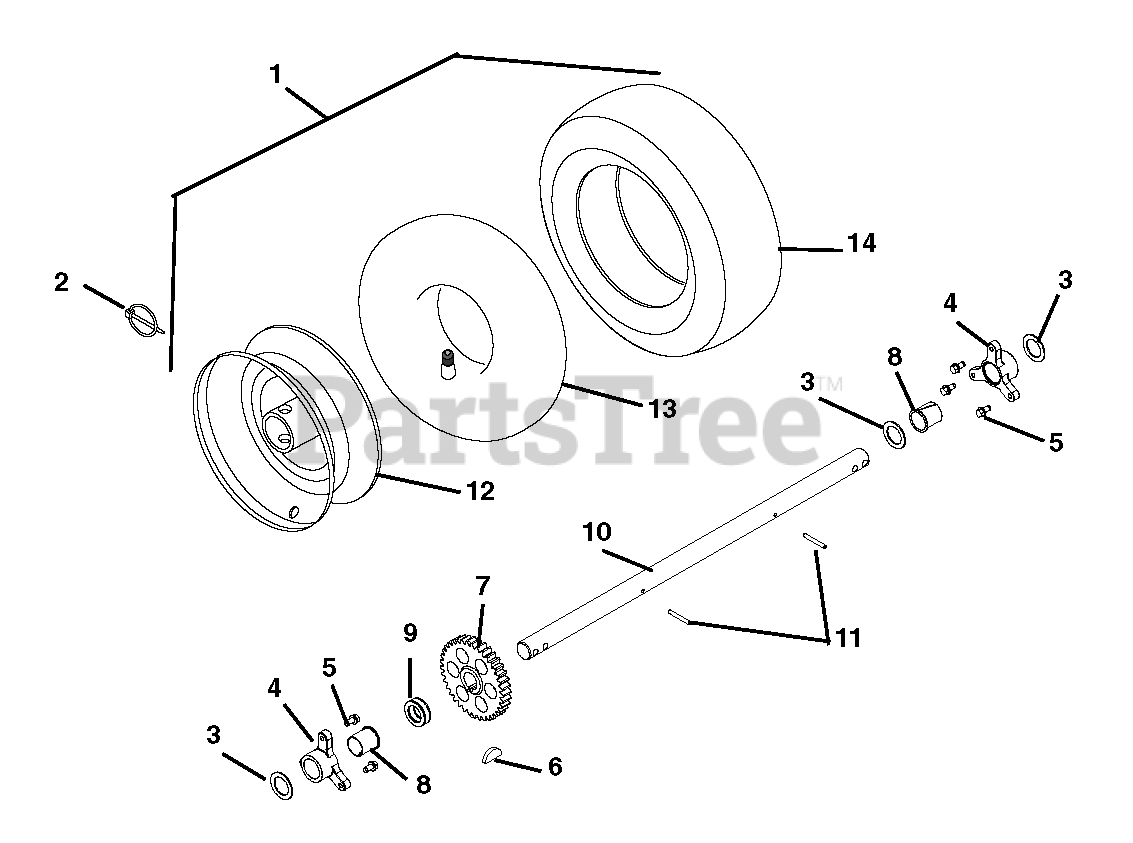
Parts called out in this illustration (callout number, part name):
1	TIRE/WHEEL, RH 15X5.00-6 PIN
1	TIRE/WHEEL, LH 15X5.00-6 PIN
2	PIN-LOK .31X2.00
3	WSHR-FL-STL 1.010X1.505X.062YZ
4	BUSHING, RAKE SHAFT 1"
5	SCR-TAP .25-20X.50 HWH TR YWZ
6	KEY-WDRF .25X.750X.313 SAE91
7	GEAR, SPUR
8	BSHG-FLG SPLIT NYLINER 1.0" HP
9	BUSHING, .50X.68X.50X.75 SLV
10	AXLE, 1.00" SOLID
11	PIN-ROLL .188X1.50
13	TUBE 15 X 5.00-6
14	TIRE, X-TRAC 15X5-6
